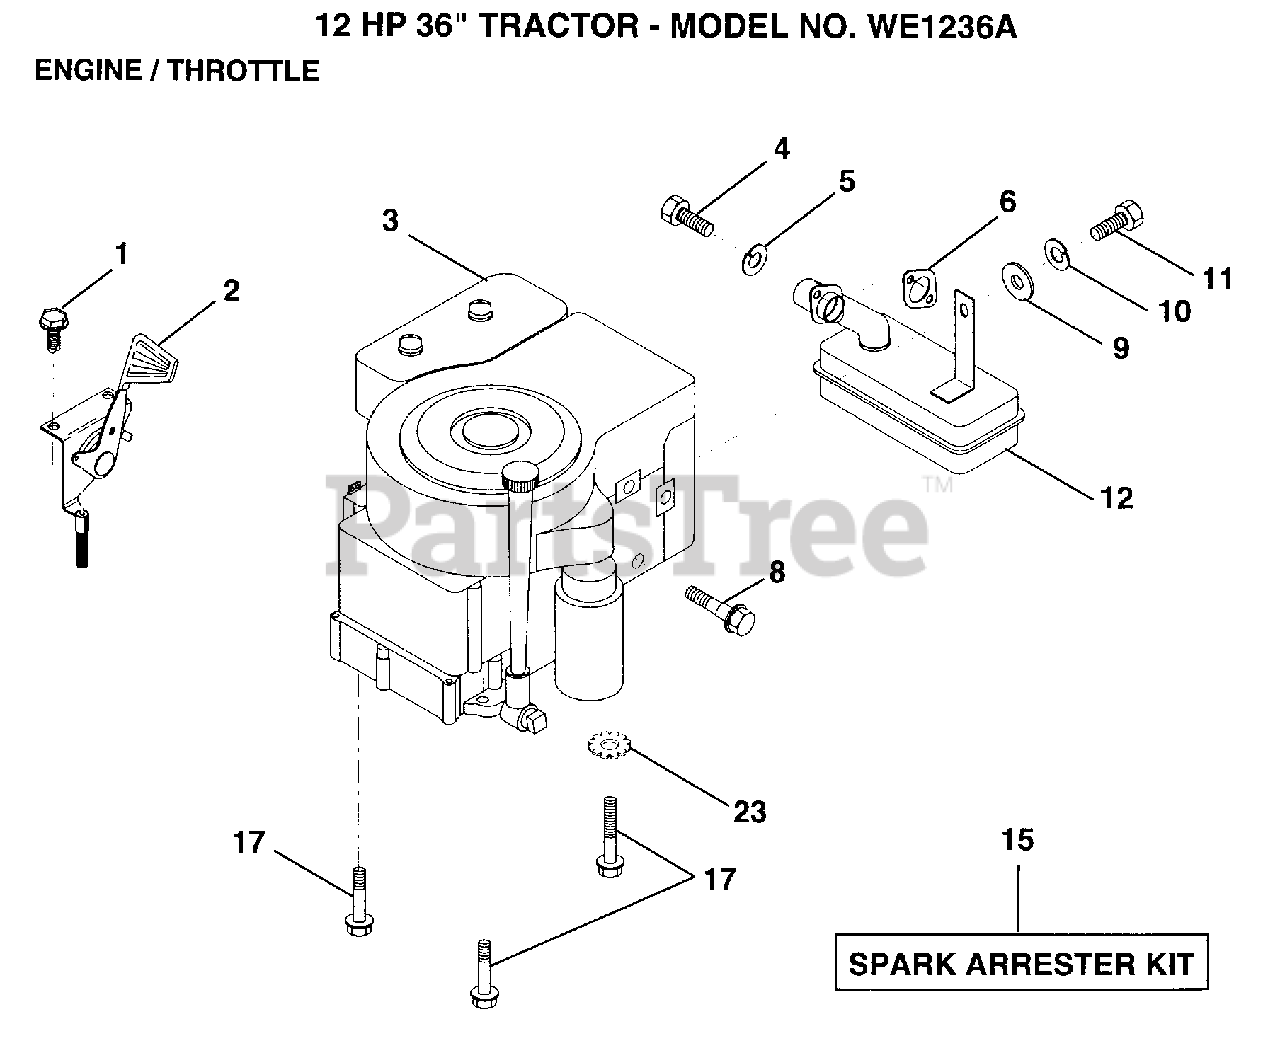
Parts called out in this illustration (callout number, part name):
1	SCREW.1/4-20X1/2
2	"CONTROL,THROTTLE"
3	ENG B&S 10-12.5HP PWRBLT DC
4	SCREW
5	LOCKWASHER
8	BOLT T
10	LOCKWASHER
12	MUFFLER
17	SCREW LT
23	LOCKWASHER
